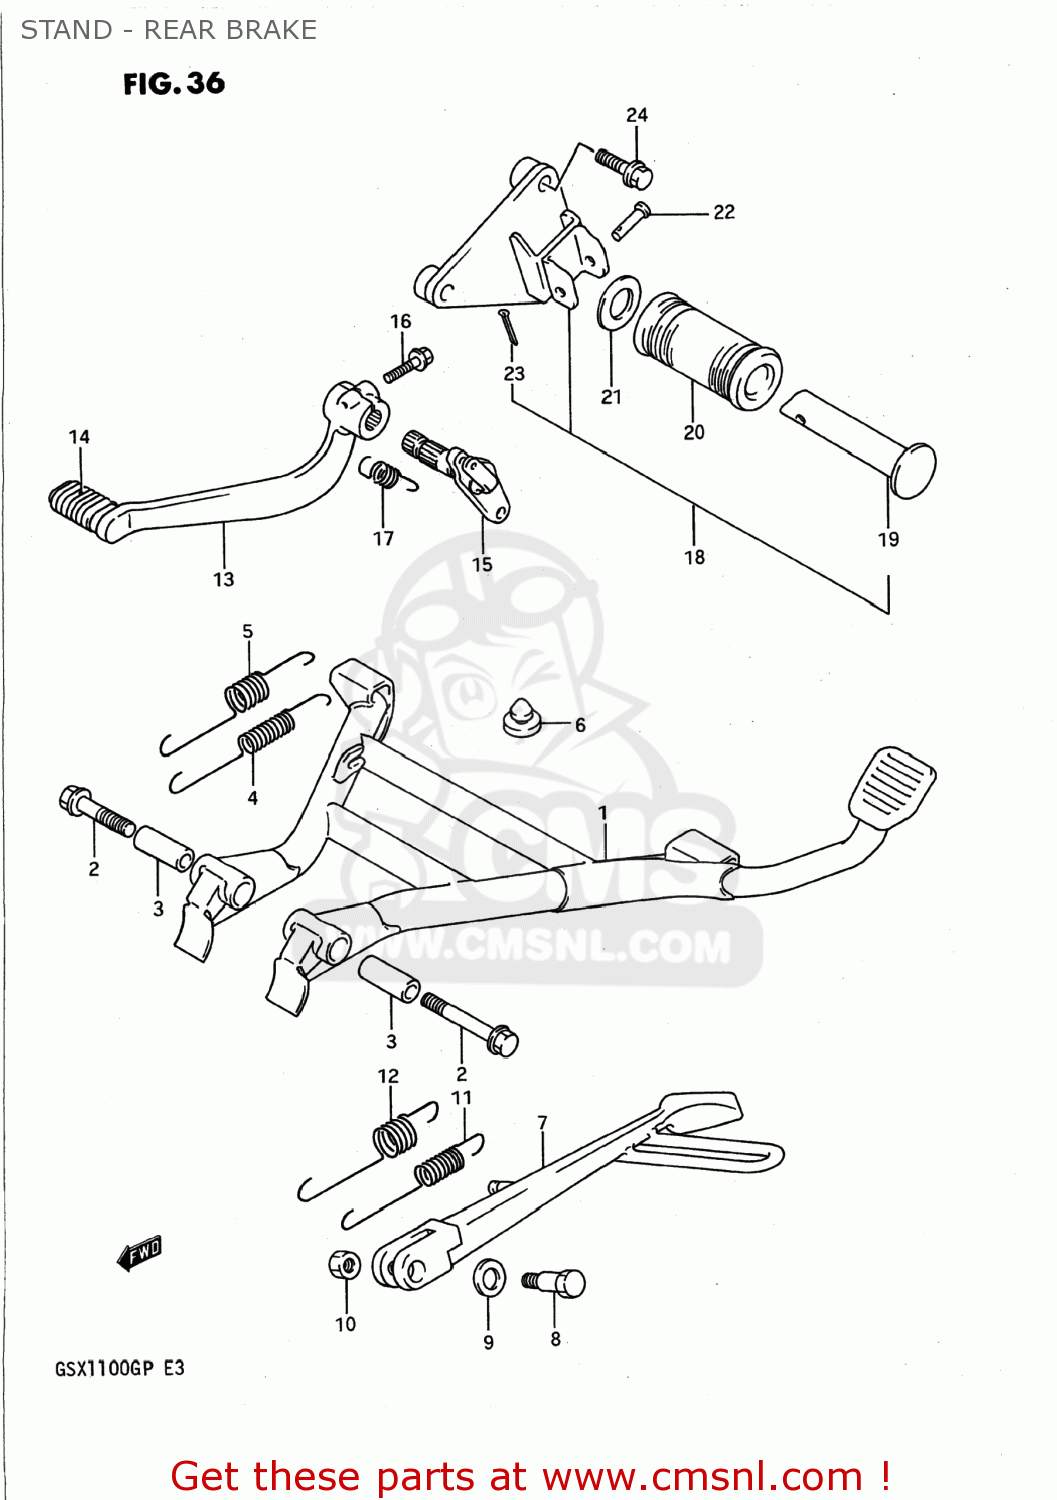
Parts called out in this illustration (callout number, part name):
1	STAND,CENTER
2	BOLT(10X60)
3	SPACER(10X16X38.8)
4	SPRING
5	SPRING OUTER
6	CUSHION
7	STAND,PROP
8	BOLT(10X38)
9	SHIM
10	NUT
11	SPRING
12	SPRING
13	PEDAL COMP,BRAKE
14	RUBBER,PEDAL
15	ARM,BRAKE ROD
16	BOLT 6X25
17	SPRING,BRAKE PEDAL
18	GRIP SET,CENTER STAND
19	BAR,PILLION FOOTREST
20	RUBBER,STAND GRIOP (OPT)
21	WASHER (19.5X32X2)
22	PIN
23	PIN
24	BOLT
